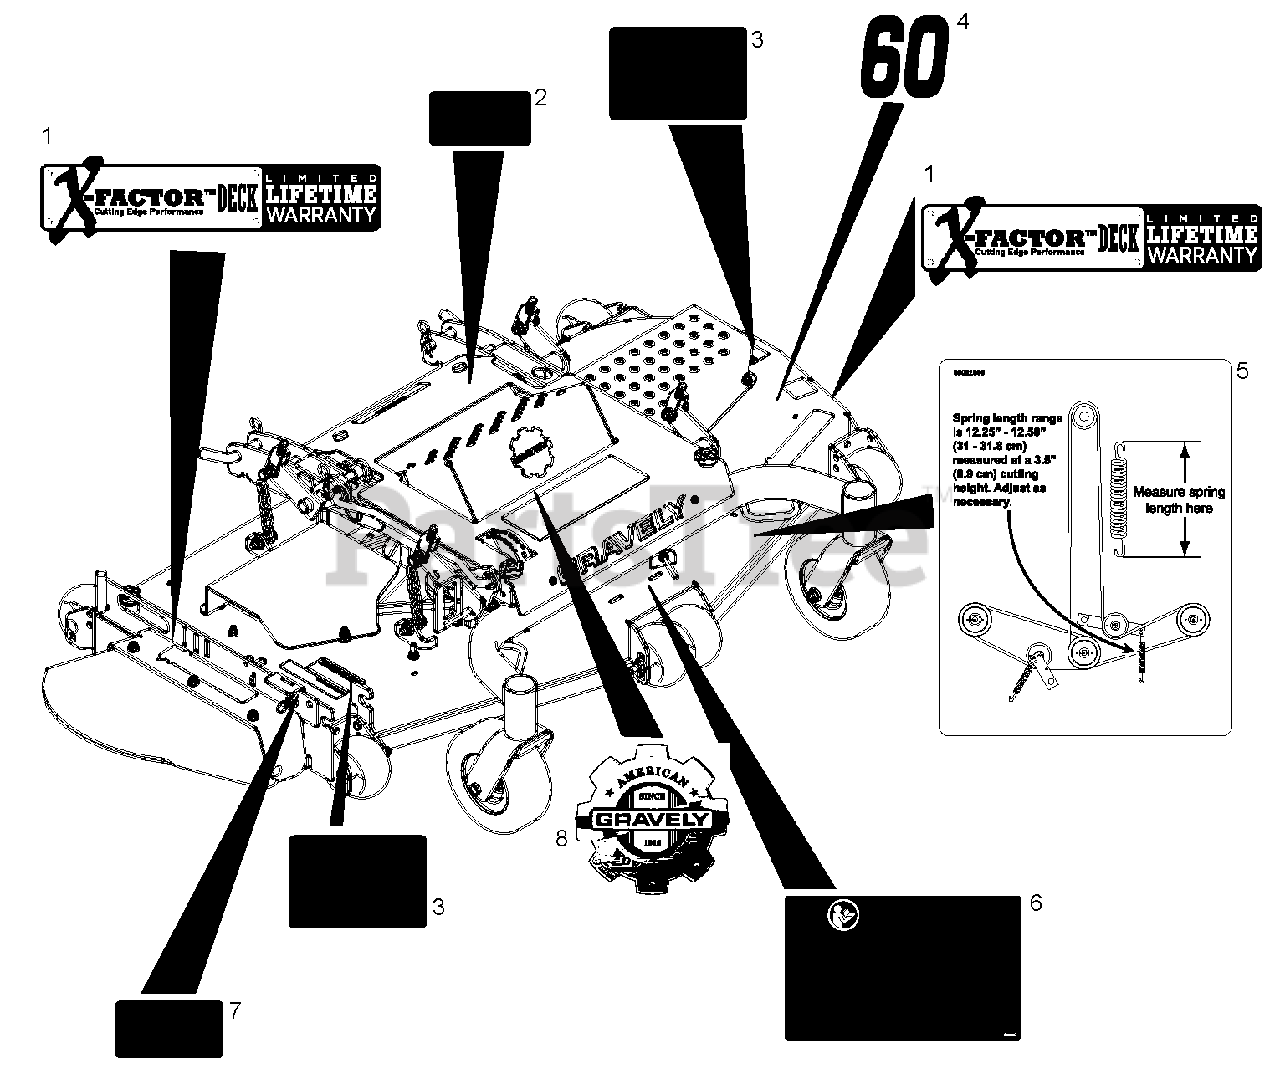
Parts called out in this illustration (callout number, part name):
1	Decal, X-Factor
2	Decal, Safety, Guarding
3	Decal, Safety, Mower Deck
4	Decal, 60
5	Decal, Belt Diagram
6	Decal, Main Safety, Commercial
7	Decal, Safety, Deck Guarding
8	Decal, Gravely Heritage
